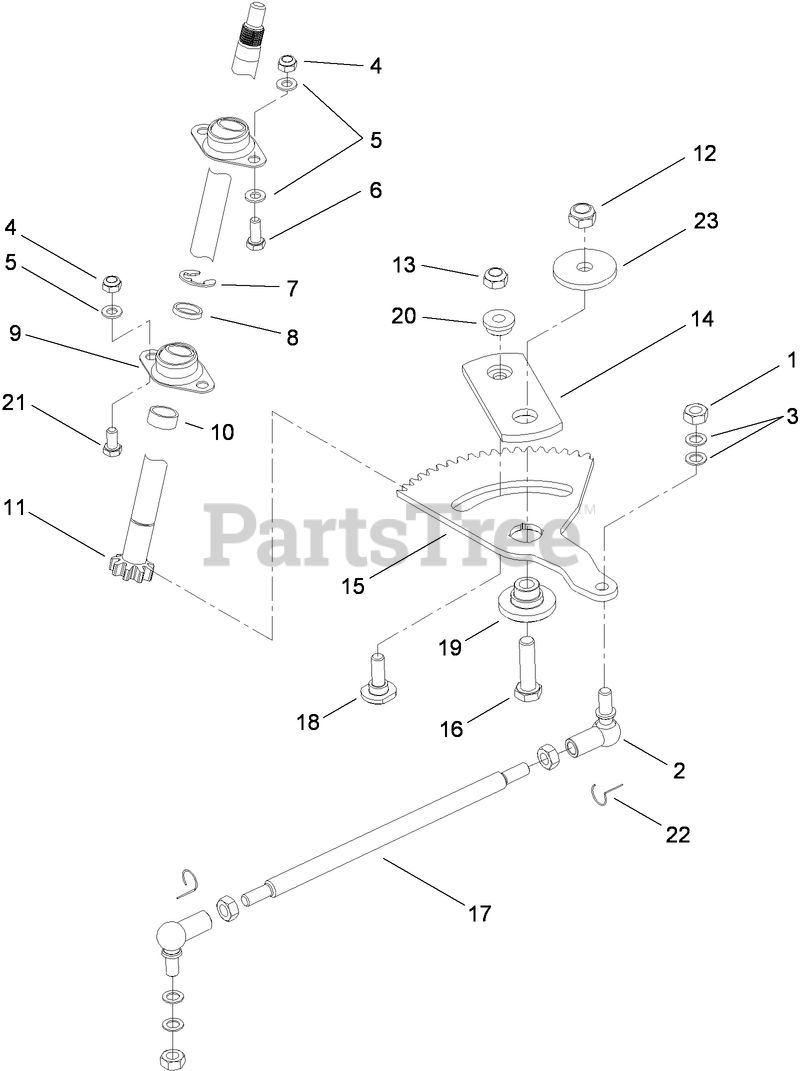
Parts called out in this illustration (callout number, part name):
1	NUT-LOCK, NI
2	JOINT-BALL, ANGLE
3	Washer
4	NUT-LOCK, NI
5	WASHER-PLAIN
6	SCREW-HH
7	CLIP-SPRING
8	SPACER-UPPER
9	BEARING-SPHERICAL
10	SPACER-LOWER
11	Shaft-Steering
12	NUT-HEX
13	NUT-LOCK, NI
14	Plate-Steering
15	GEAR-SECTOR
16	SCREW-HH
17	LINK-DRAG
18	Bolt-Shoulder
19	Pivot-Steering
20	Bushing
21	SCREW-HH
23	WASHER
